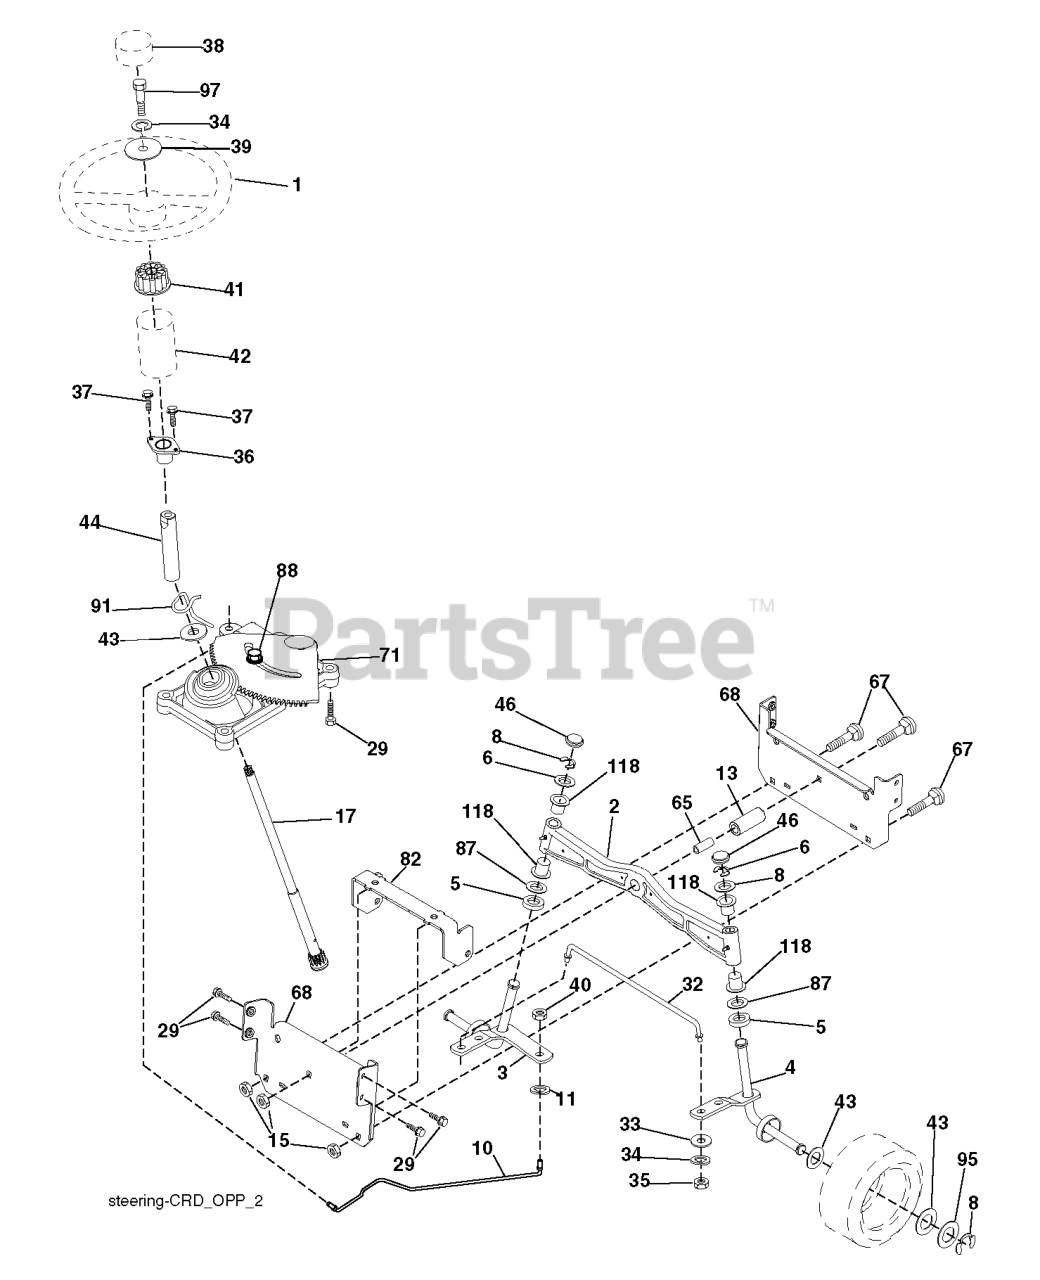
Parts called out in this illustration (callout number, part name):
1	RP WHEEL.STEER.HUSQ.PREM.OVMLD
2	AXLE.ASM.LT.CAST.LGHTWGHT
3	SPINDLE.ASM.LH.15"TIRES
4	SPINDLE.ASM.RH.15"TIRES
5	THRUST WASHER
10	DRAGLINK.15".TIRES.2001
11	WASHER, LOCK 3/8
13	TUBE, PIVOT AXLE
15	NUT
17	SHAFT STEERING SPLINE
29	SCREW, 3/8-16X3/4
33	WASHER M
34	WASHER.LOCK.HVY.HLCL.SPR.5/16
35	NUT, CROWNLOCK
36	BUSHING, STEERING
37	SCREW.TT.#10-32X.5.3/8.FLANGE
38	RP INSERT.CAP.WHL.STRG.HUSQ.
39	WASHER.11/32
40	NUT CROWNLOCK 3/8-24
41	ADAPTER, WHEEL STNG..
42	BOOT, STEERING
44	SHAFT.EXTEN.STRG.SPLINE
46	CAP.SPINDLE.BLACK
65	SPACER.BRACE.AXLE
67	BOLT CARRIAGE
68	BRACE.AXLE.15"TIRES
71	STEERING ASM
82	BRACKET.SUSP.CHASSIS.FRONT.15
87	WASHER, FLAT .781 X 1 1/2"
88	BOLT, SHOULDER 7/16-20
91	CLIP.STEERING
95	WASHER.HARDENED
97	BOLT 5/16-18 X 4 W/PATCH
118	BUSHING, AXLE CAST
